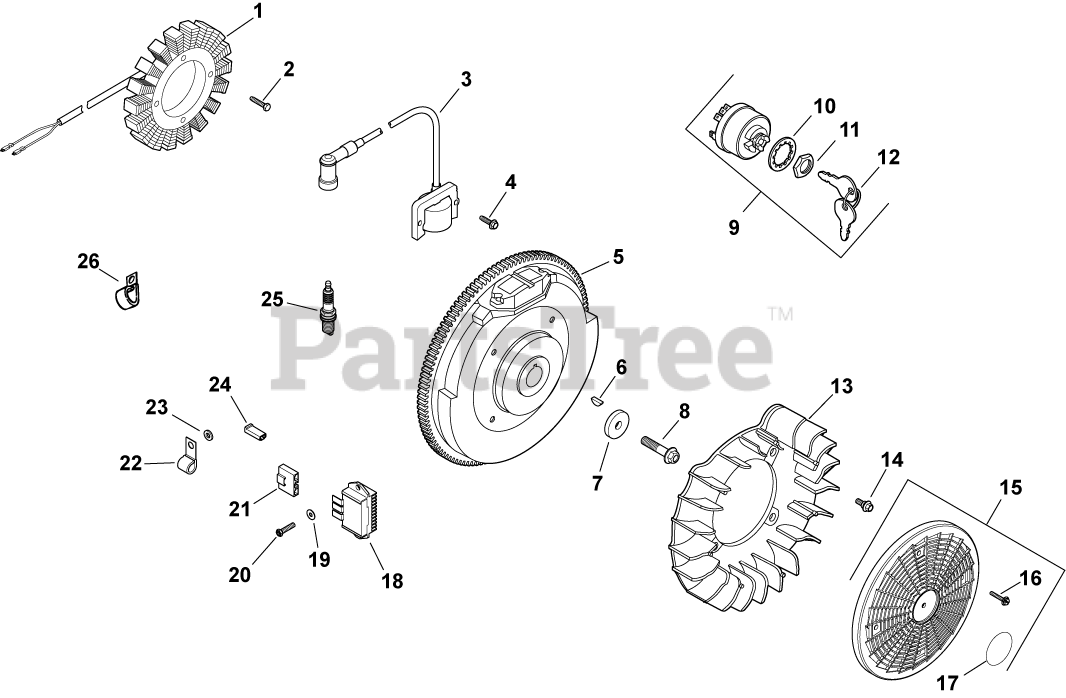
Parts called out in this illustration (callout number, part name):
1	KIT, 15 / 20 AMP STATOR
2	SCREW, M5X0.8X25 - (#25086402S)
3	KIT, MODULE IGNTN (CDI FIXED)
4	SCREW, FLG THD FRM M5X.8X20-(#25086399S)
5	FLYWHEEL, PAINTED-USE 24 025 55-S
6	KEY, 3/16" X 5/8"
7	WASHER, FLAT 13/32"
8	SCREW, FLG M10X1.5X45 - (#25086361S)
9	SWITCH ASSY, KEY (KM)-USE 25 099 32-S
10	WASHER, INTERNAL TOOTH
11	NUT, KEY SWITCH
12	KEY, SET -USE 48 340 01-S
13	FAN USE 24 755 253-S
14	BOLT, SHOULDER
15	KIT, GRASS SCREEN
16	SCREW, FLG SEMS M4X.7X25
17	DECAL, GRASS SCREEN USE 24 113 499-S
18	REG/RECTIFIER (20/25 AMP)-USE 25 403 20-
19	WASHER, FLAT 7/32"
20	SCREW, PHL HD #11-16X7/8"
21	CONNECTOR, BODY (KM)-USE 25 155 41-S
22	CLIP, CABLE
23	WASHER, FLAT 1/4" (O.D. 1/2")
24	CONNECTOR (1 CONTACT)
25	PLUG, SPARK (PRO SERIES)
26	CLIP, TUBE & WIRING (KM)
